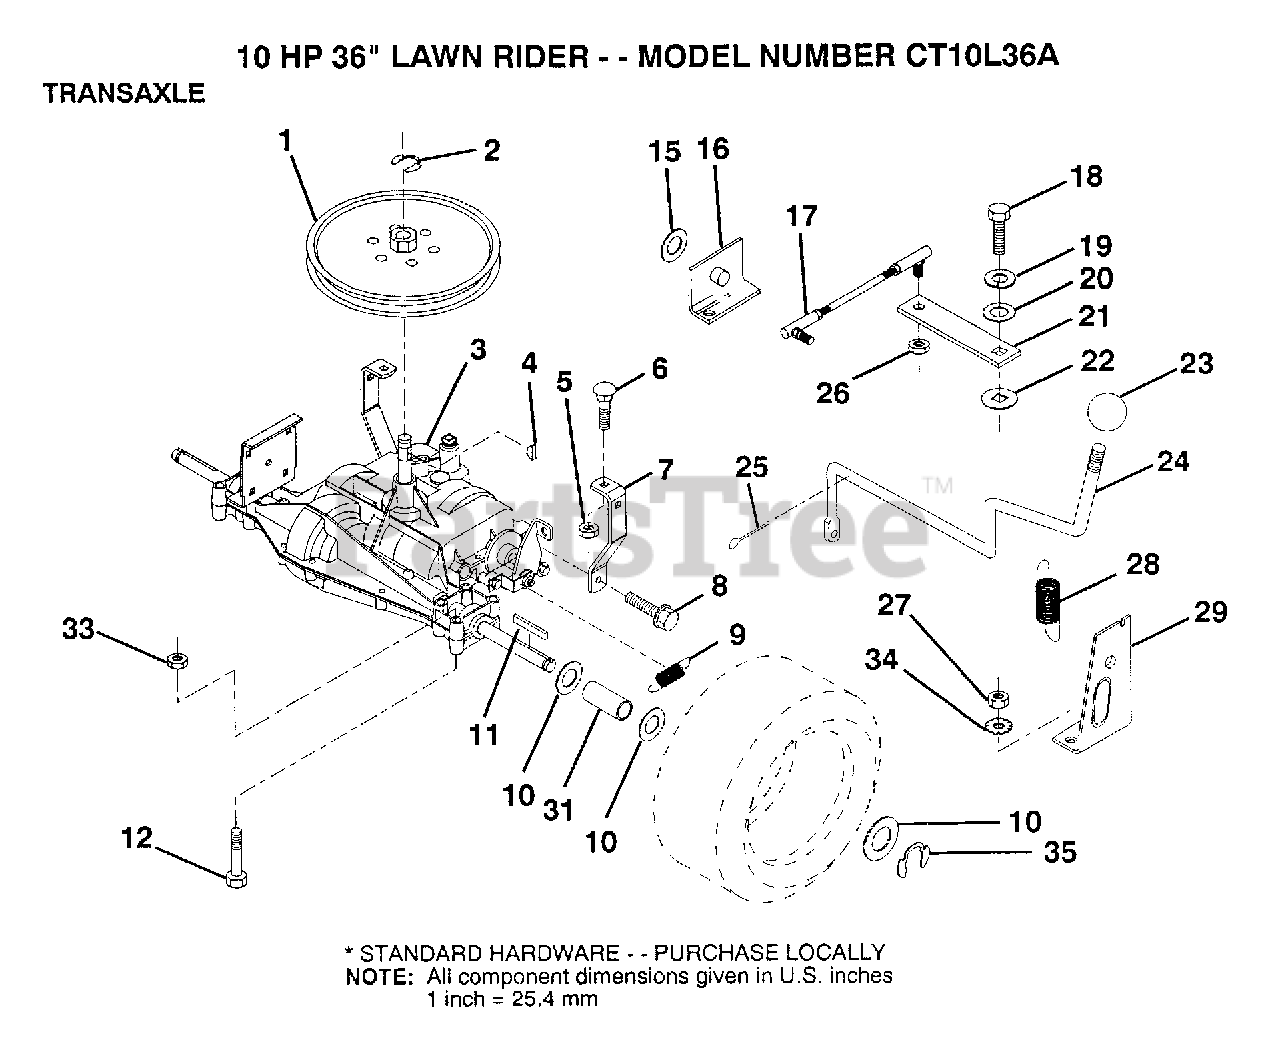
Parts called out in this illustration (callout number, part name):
1	PULLEY
3	PULLEY
6	BOLT
7	"STRAP,TORQUE"
8	SCREW
10	WASHER
11	SQUARE KEY
12	BOLT
16	"SUPT,HDLE SHT LH"
17	"LINK,SHIFT"
19	LOCKWASHER
20	WASHER LT
21	ARM SHIFT
22	WASH-SHFT PLT LT
23	KNOB T (1/2-HOLE)
24	"ROD,SHIFT"
25	PIN COTTER 1/8
26	NUT.LOCK.5/16-24
28	"SPRING,EXT"
29	"SUPT,HDLE RH"
31	SPACER
34	LOCKWASHER.5/16.E
35	E-RING LT
